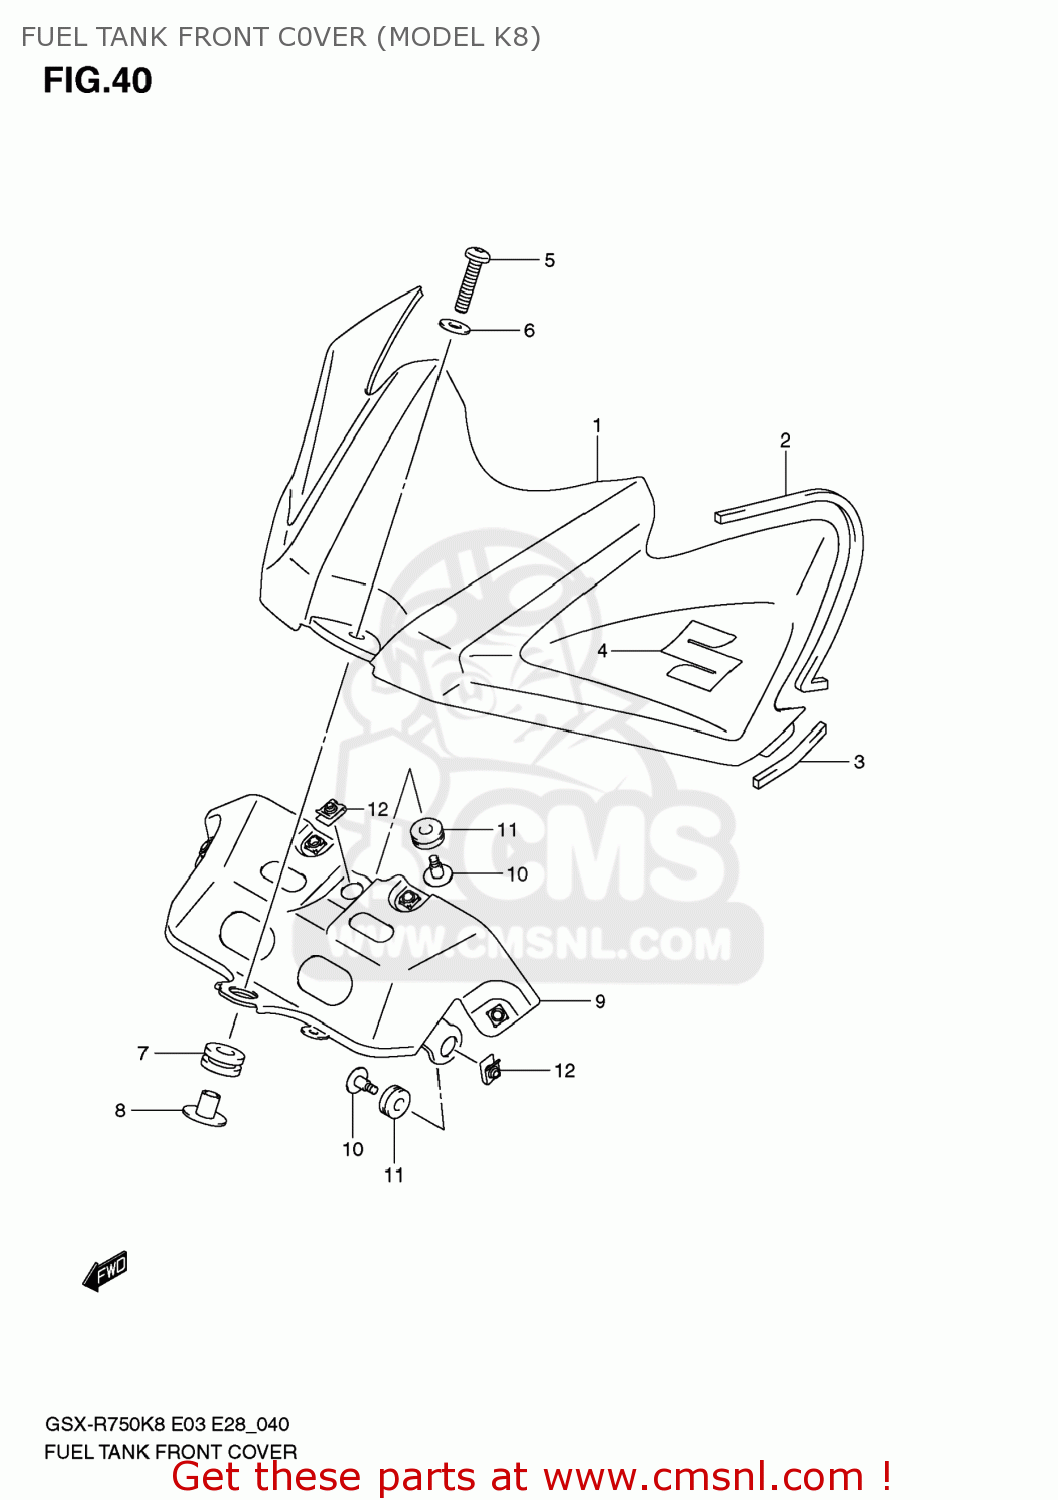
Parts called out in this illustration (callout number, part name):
1	COVER,FUEL TANK FR
2	CUSHION,FUEL TANK COVER
3	CUSHION,FUEL TANK COVER NO.2
4	EMBLEM,S
5	BOLT(8X37)
6	WASHER(8.5X24X1.6)
7	CUSHION
8	SPACER(8.6X12X16.1)
9	BRACKET,FUEL TANK FR
10	SCREW(5X16.4)
11	CUSHION
12	NUT
